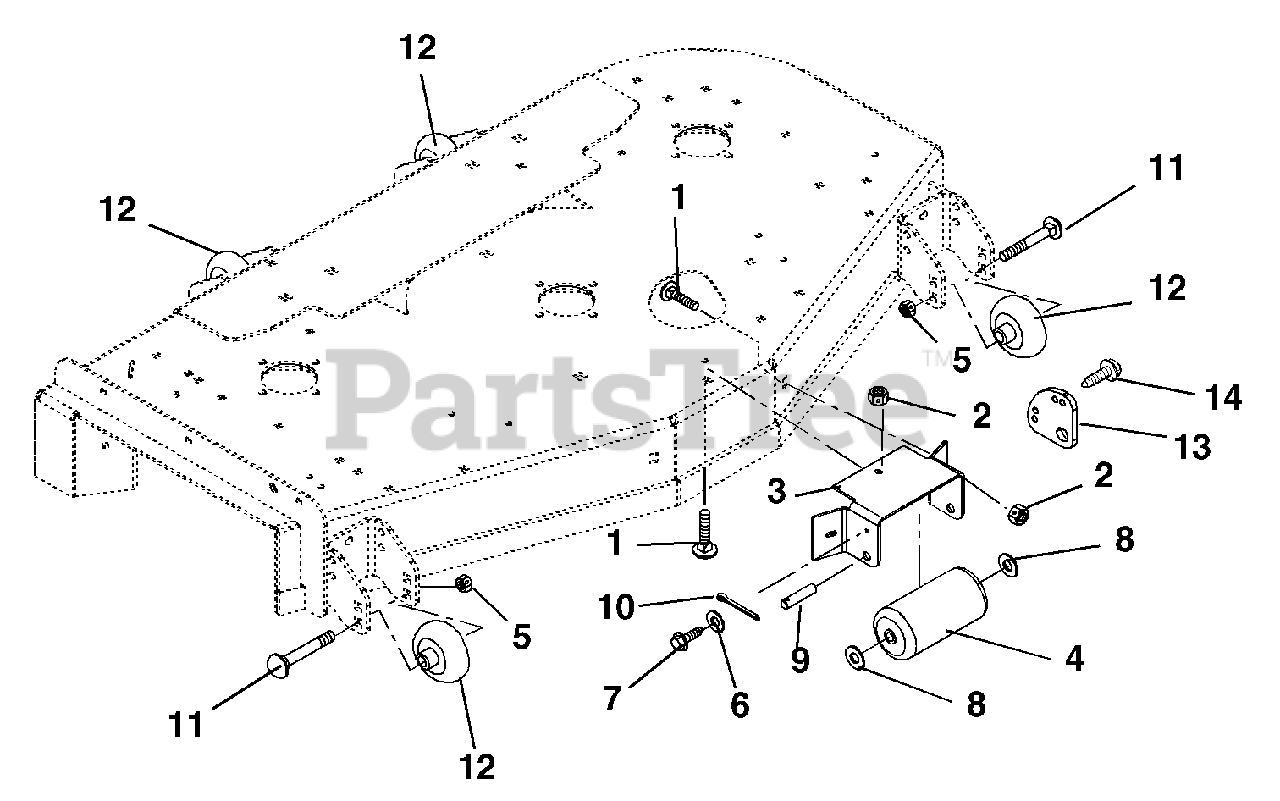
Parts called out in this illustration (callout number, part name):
1	Bolt-Round Head Square Neck .38-16 x 1.00 Grade 5 (042, 043, 044, 310, 311)
1	Bolt-Round Head Square Neck .38-16 x 1.25 Grade 2 (051)
2	Nut-Locking-Top-Flange .38-16
3	Bracket- Anti-Scalp Roller (042, 310)
3	Bracket- Anti-Scalp Roller (043, 044, 311)
3	Bracket, Anti-Scalp Roller (051)
5	Nut-Locking-Top-Flange .50-13
6	Washer-Flat-Steel .281 x .62 x .065
7	Screw-Tapping .25-20 x .75 Hex Washer Head
8	Washer-Flat-Steel .656 x 1.31 x .095
10	Pin-Cotter .25 x 2.0
11	Bolt-Round Head Square Neck .50-13 x 5.00 Grade 2
12	Wheel, 3 x 5
13	Anti-Scalp Washer
14	Screw-Tapping .25-20 x .62 Hex Washer Head
